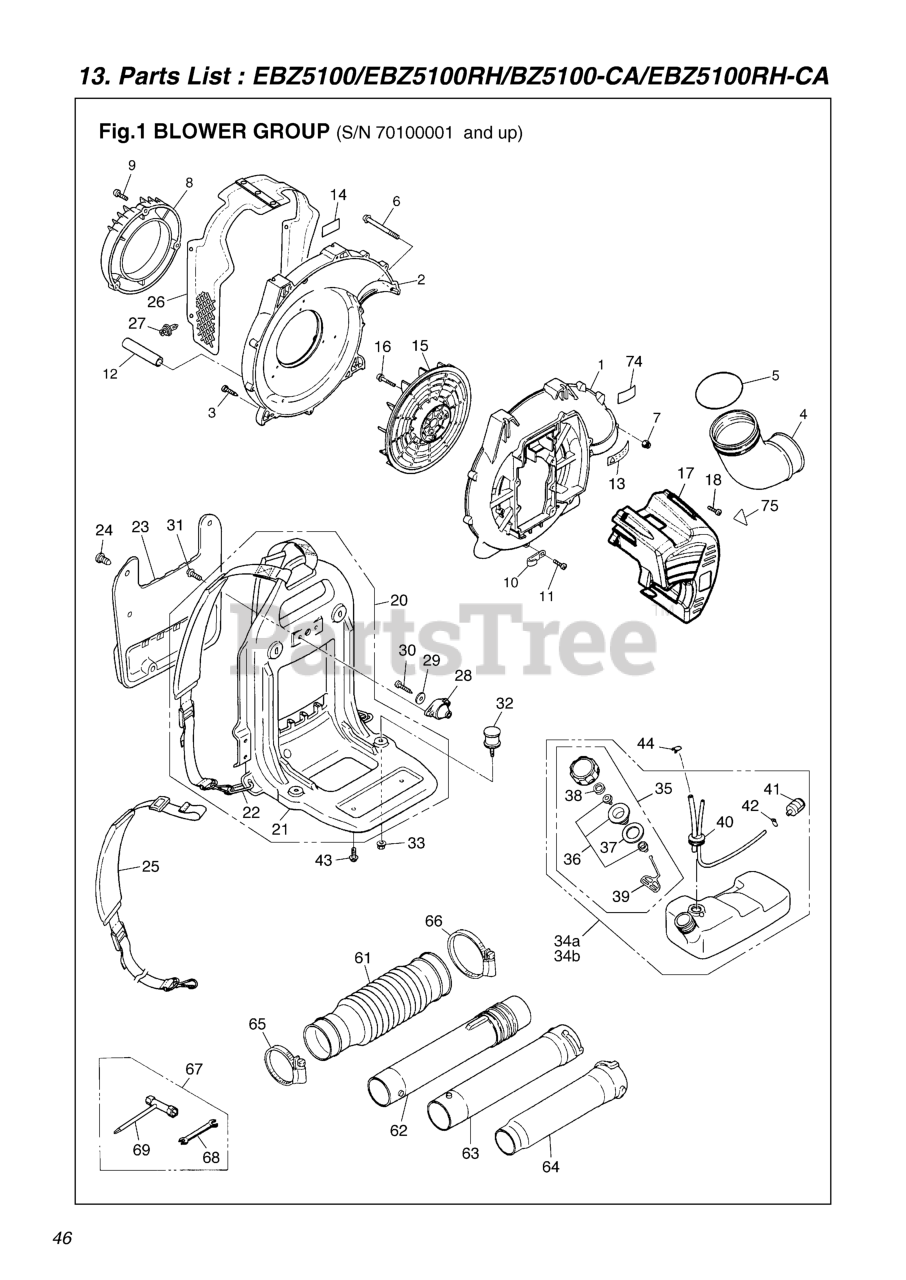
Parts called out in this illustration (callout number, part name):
1	CASE, VOLUTE
2	COVER, VOLUTE
3	SCREW
4	ELBOW
5	O-RING
6	BOLT,TORX, M5X70
7	NUT (B)
8	FUNNEL
9	SCREW
10	CLAMP
12	TUBE (RPLS. 07270-01507)
13	LABEL, CAUTION (RPLS -31910)
14	LABEL, NET
15	FAN
16	BOLT
17	ENGINE COVER
18	SCREW
20	FRAME ASSY
21	FRAME COMP
22	RING (REPLACES -21120)
23	PAD
24	CLIP (RPLS 3490-21320)
25	BAND ASSY
26	NET COMP
27	CLIP
28	DAMPER, UPPER
29	WASHER
30	SCREW (RPLS T4970-54010)
31	SCREW TORX
32	DAMPER, LOWER
33	NUT, M6
34A	TANK ASSY
35	CAP ASSY (RPLS -85201)
36	HOLDER (REPLACES -85230)
37	PACKING
38	FILTER
39	STOPPER
40	PIPE COMPLETE
41	FILTER ASSY
42	CLIP (REPLACES 2841-31280)
43	SCREW TORX
44	CLIP
61	HOSE
62	SWIVEL-JOINT (REPLACES -51200)
63	PIPE, STRAIGHT
64	PIPE, END
65	CLAMP
66	CLAMP
67	TOOL-SET
68	SPANNER, 8 X 10 (RPLS 2540- )
74	LABEL, SOUND
75	LABEL, HOTMARK
